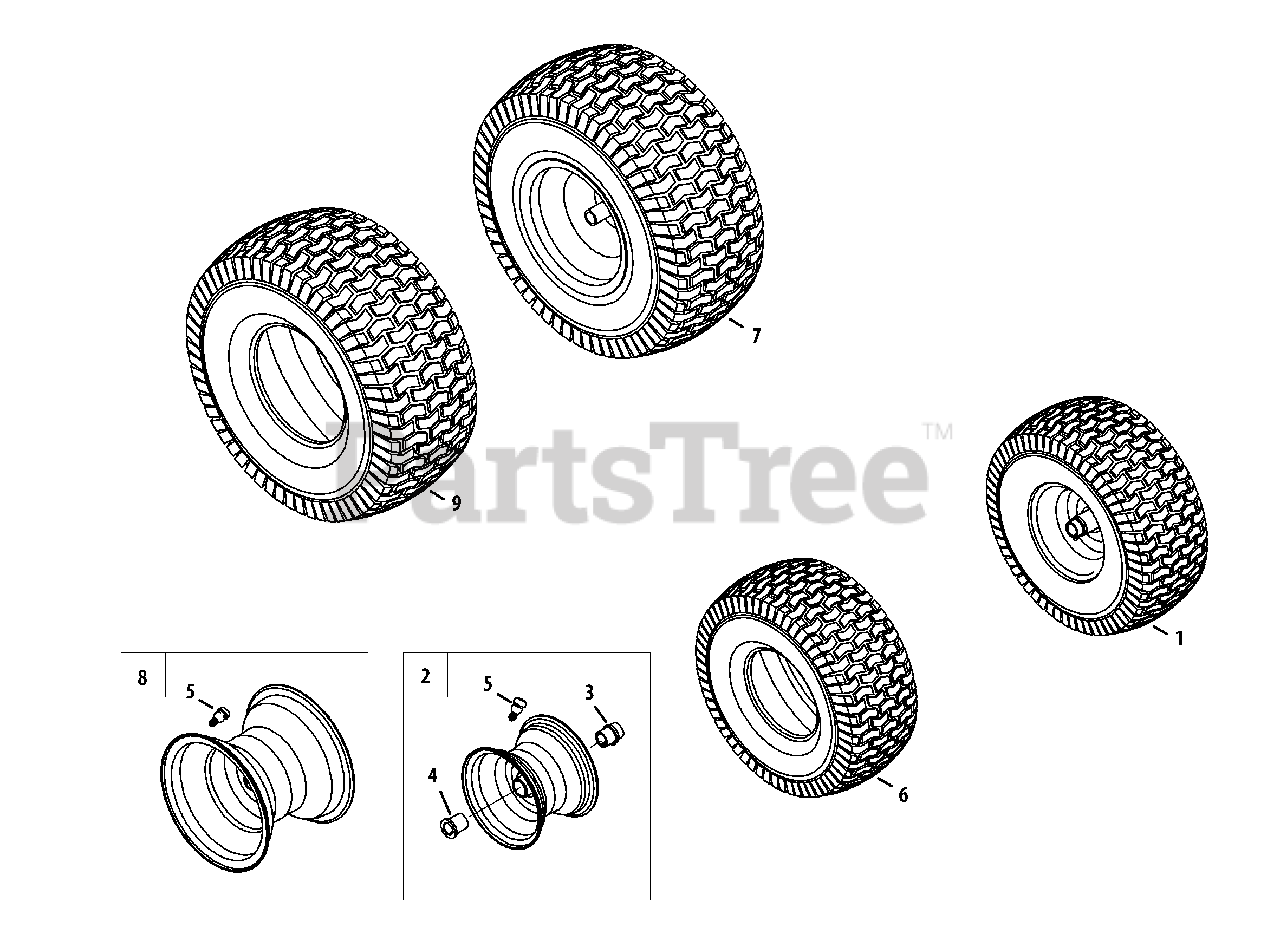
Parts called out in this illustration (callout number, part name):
1	Wheel Ass’y, Complete, 15 x 6 x 6
2	Rim Ass’y, 6.0 x 4.5, Flange Bearings
3	Bearing, Flange, .760 ID w/ Fitting
4	Bearing, Flange, .760 x 1.00 x 1.20
5	Valve, Tubeless Air
6	Tire, 15 x 6 x 6 Sq Shoulder
7	Wheel, Complete, 20 x 8 x 8
8	Rim Ass’y, 8.0 x 7.0 x .750 ID
9	Tire, 20 x 8 x 8 Sq Shoulder
